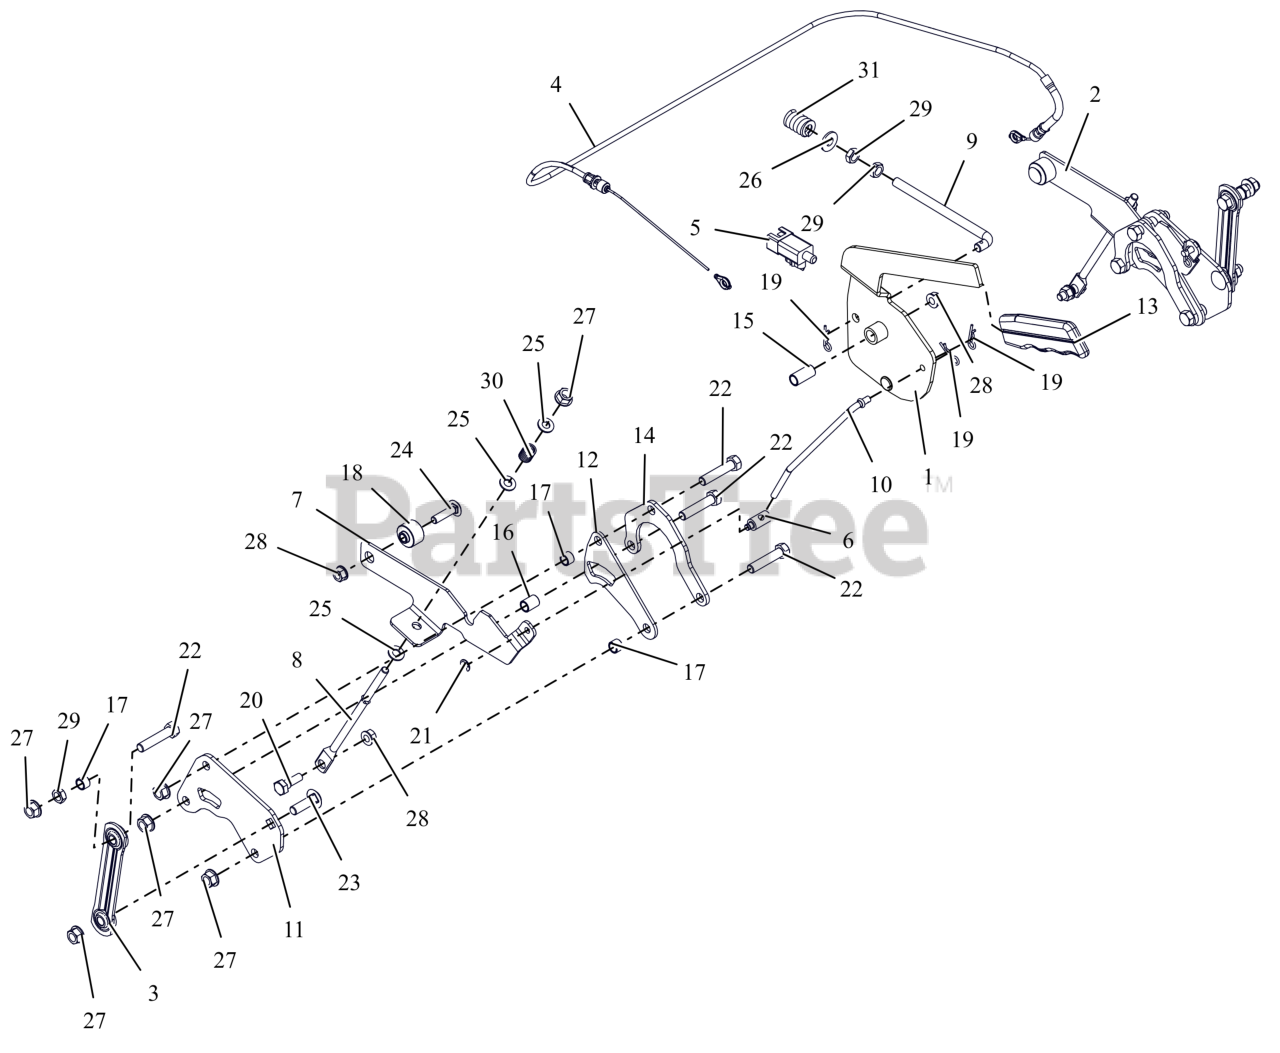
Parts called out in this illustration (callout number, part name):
1	LEVER, PARKING BRAKE
2	ARM, BRAKE - LH (W/PIN)
3	LINK, STAMPED STEERING
4	CABLE, BRAKE - PARKING
5	SWITCH, SNAP IN - N.O./N.O.
6	TRUNION, 1/4-20
7	ARM, BRAKE-RH
8	ROD, LINK - TRANSMISSION BRAKE
9	ROD, OVER CENTER
10	ROD, BRAKE LINK
11	BRKT, TRANSAXLE STEERING
12	BRKT-SPACER
13	GRIP, PARKING BRAKE (YELLOW)
14	PLATE, REAR REINFORCING
15	BSHG-SLV .385X.500X1.045
16	SPCR, SLV .385X.500X.652
17	SPCR, SLV .385X.500X.350
18	SPCR, FLANGE
19	PIN, HAIR #213 .08X1.19 ZCC
20	BOLT,SHLDR .38X.25 -.31-18X.75
21	RG-RTNG-EXT .250X.025
22	BLT, HEX .38-16X1.75 G5 ZCC
23	BLT,RHSSN .38-16X1.25 G5 ZCC
24	BLT, RHSSN.31-18X1.25 G5 ZCC
25	WSHR,FLT .344X.688X.065 ZCC
26	WSHR,FLT .375X.875X.083 ZCC
27	NUT-LK-TOP-FLG .38-16 ZC120
28	NUT-LK-TOP-FLG .312-18 GF ZCC
29	NUT-JAM .375-16 G2 ZCC
30	SPRING, COMPRESSION
31	SG-COMP .187X.56X1.62
